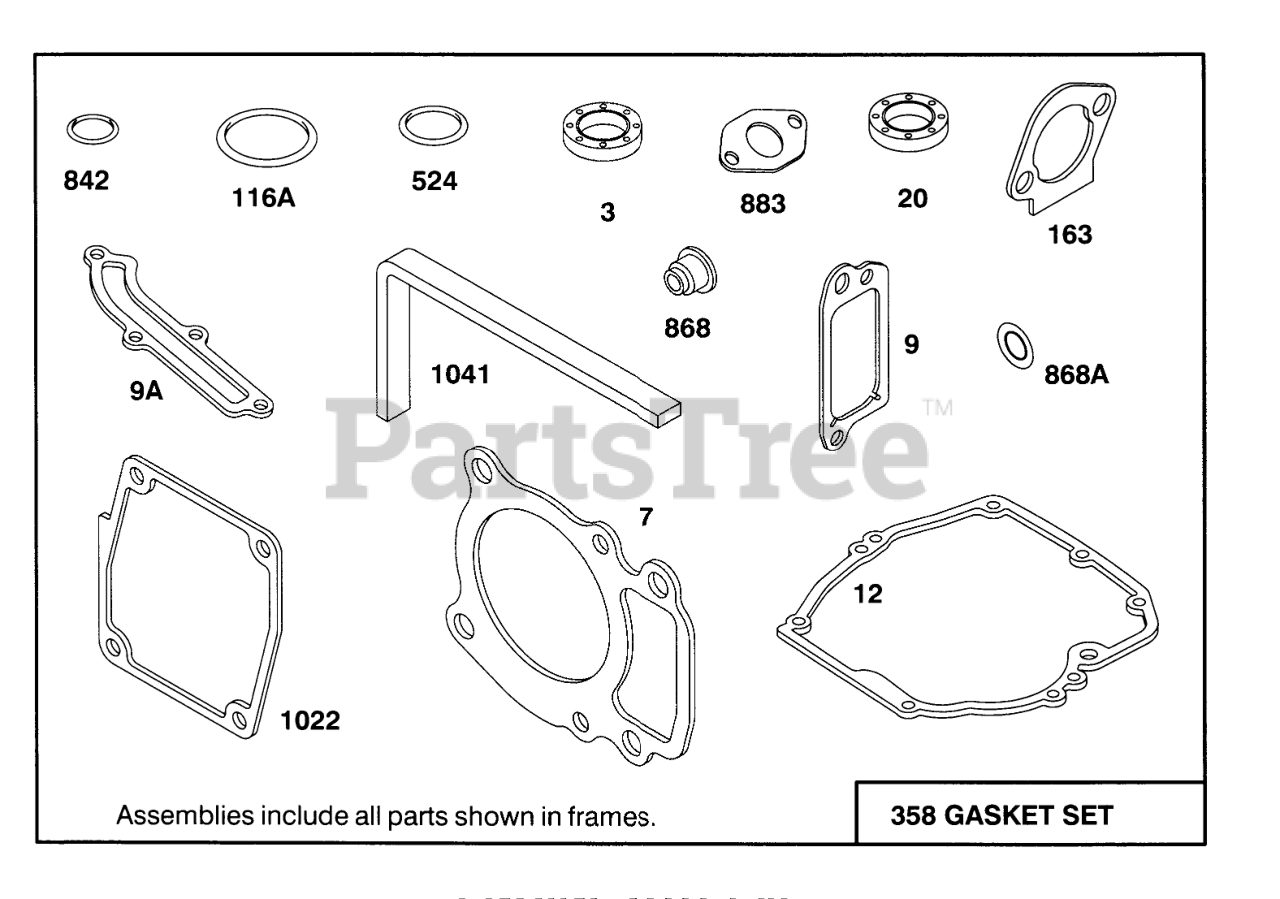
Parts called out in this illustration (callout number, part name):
3	SEAL - OIL
7	CYLINDER HEAD GASKET
9	BREATHER GASKET
9A	GASKET-BREATHER
12	ENGINE BASE GASKET
20	SEAL-OIL
116A	O RING SEAL
163	AIR CLEANER GASKET
358	GASKET SET
524	O-RING
842	O-RING
868	SealAssy-Valve
868A	Seal-Valve
883	EXHAUST GASKET
1022	ROCKER COVER GASKET
1041	SEAL - FOAM
